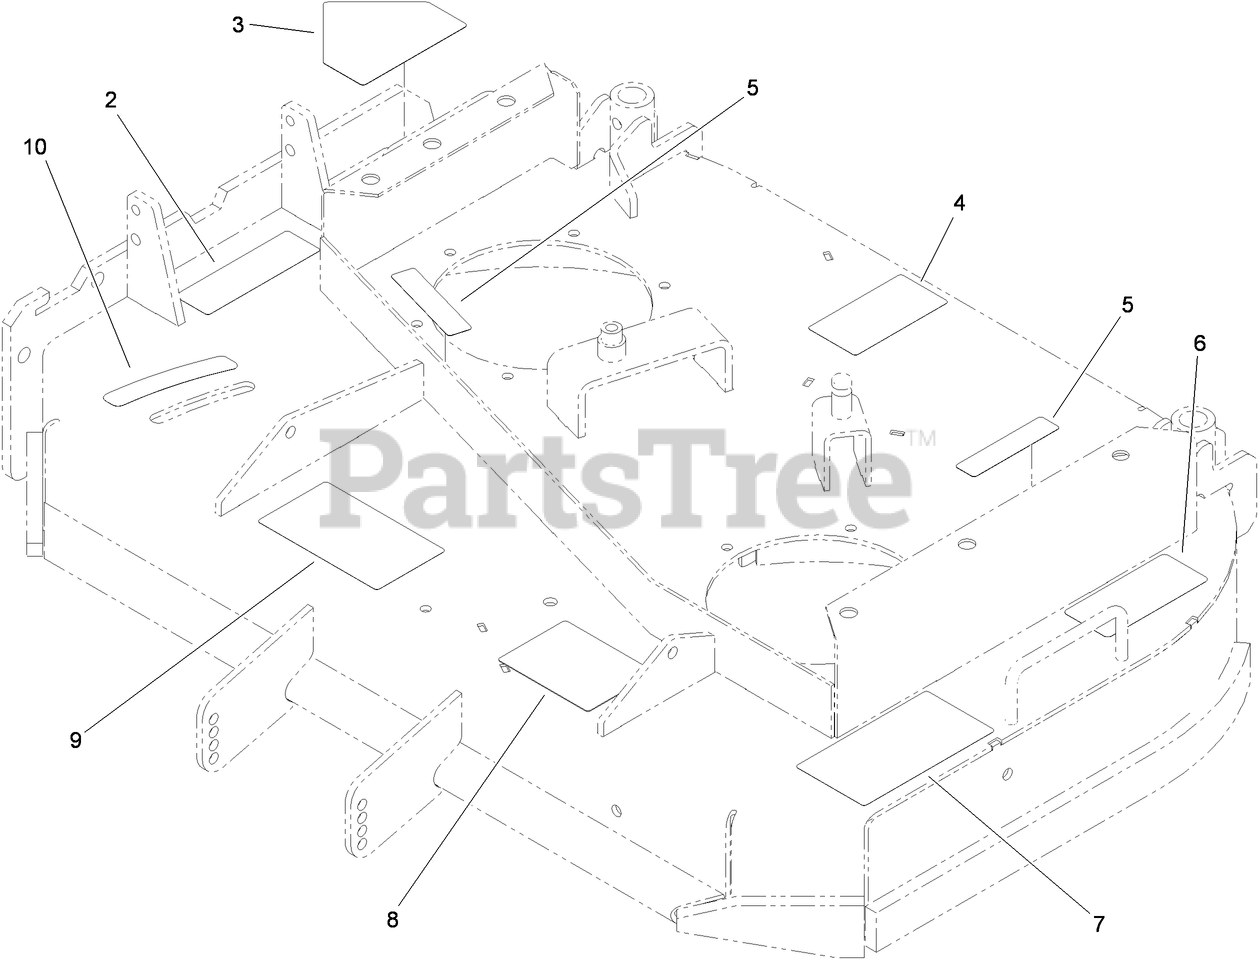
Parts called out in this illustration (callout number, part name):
2	DECAL-WARNING
3	DECAL-DANGER
5	DECAL-COVER, MISSING
6	DECAL-TORQUE
7	DECAL-DANGER, THROWN OBJECT
8	DECAL-SCALP, ANTI
9	DECAL-ADJUSTMENT, BAFFLE
10	DECAL-SETTING, BAFFLE
